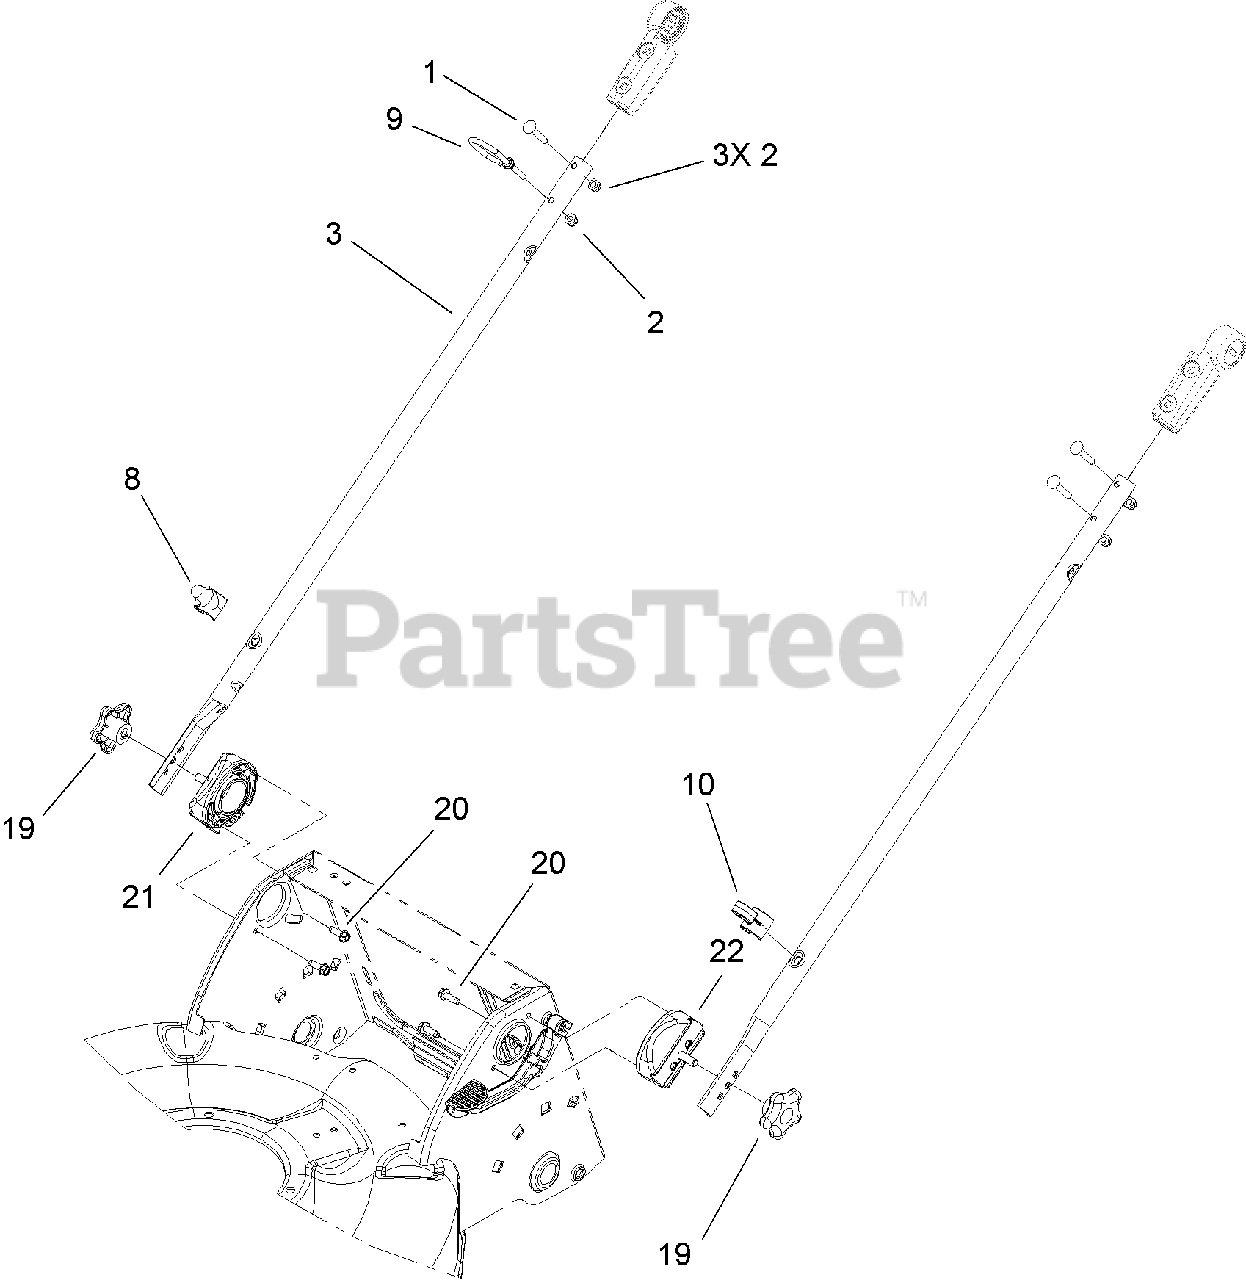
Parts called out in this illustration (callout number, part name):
1	SCREW-CARR
2	NUT-LOCK, NI
8	GUIDE-ROPE, LOWER
9	GUIDE-ROPE, UPPER
10	Guide-Cable
19	KNOB-HANDLE
20	SCREW-HWHTF
21	RH HANDLE MOUNT ASM
22	LH HANDLE MOUNT ASM
